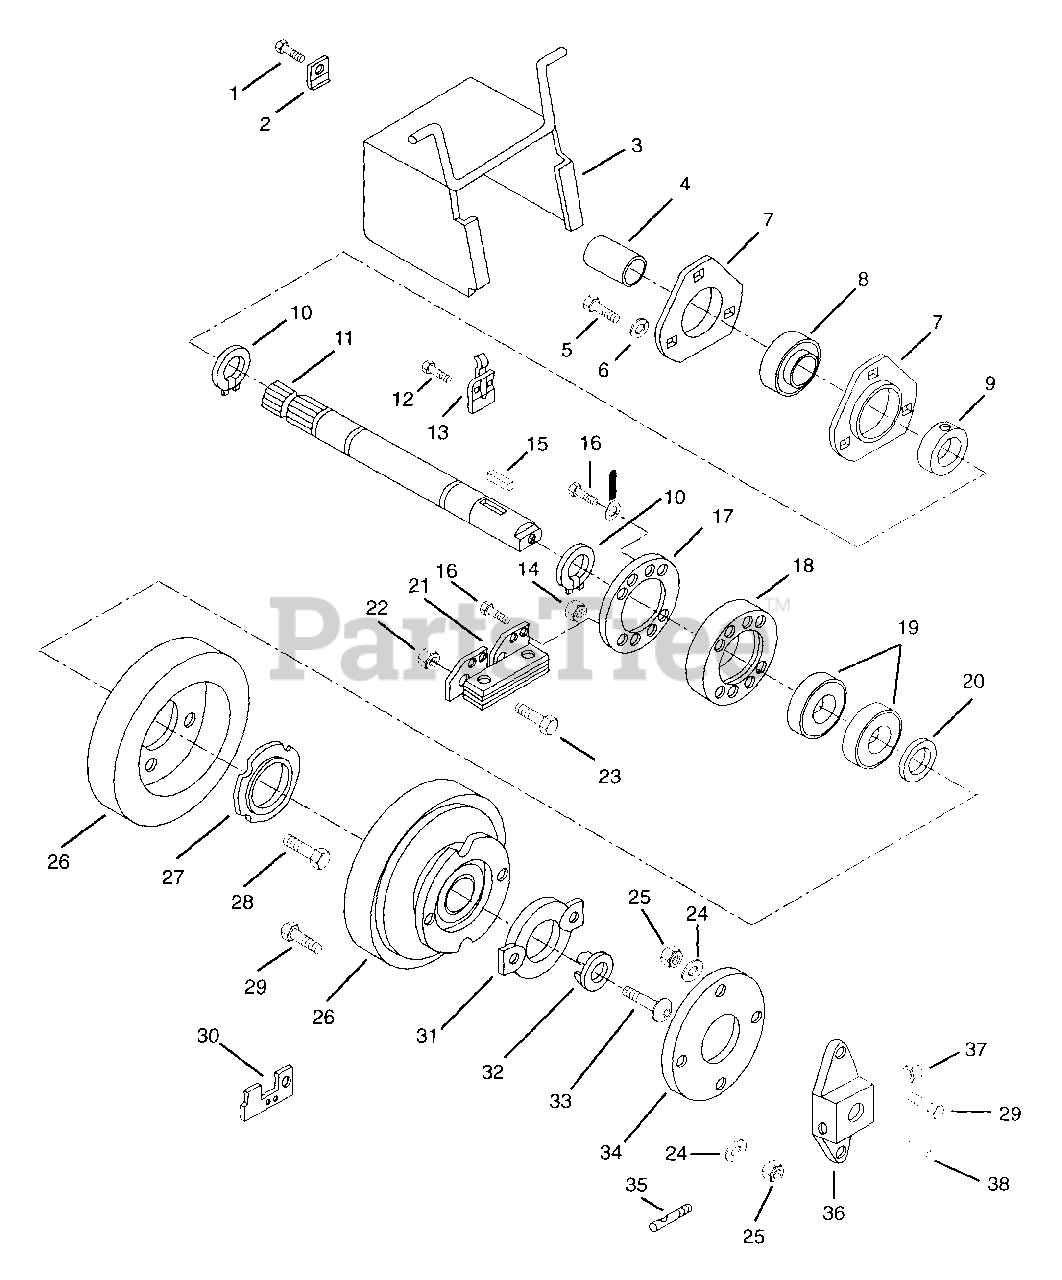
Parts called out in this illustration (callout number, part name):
1	SCR-TAP .250-20X.50 HXSLHDPL
3	PTO SHIELD
4	SHAFT COVER
5	BLT-HEX .31-18X.75 PL GR2
6	WSHR-LK .312X.097 PL HVY
7	BEARING FLANGE
8	BRG/W COLLAR 1.0 X 2.047 X.844
9	BEARING COLLAR
10	RG-RTNG-EXT 1.00X.078
12	SCR-TAP 10-24X.375 HWH PL TR
13	SNAP FASTENER
14	NUT-LK TOP 10-24 PL
15	KEY-SQ .25X1.0X.25 SAE 8630
16	SCR-TAP 10-24X.75 HWH PL TR
18	BEARING MOUNT
19	BRG-BALL 1.0X2.0X.56 (1641)
20	WSHR-FL-STL 1.031X1.375X.055
21	TORQUE BRACKET ASSEMBLY
22	NUT-LK-CTR .312-24 PL
23	BLT-HEX .31-18X1.50 PL GR5
24	WSHR-FL-STL.344X.688X.065PL
25	NUT-LK .312-18 GR A PL
26	ELECTRIC CLUTCH
27	BEARING FLANGE
28	SCR-MCH 10-24X1.25 SLPAN PL
29	BLT-HEX .31-18X.88 PL GR2
30	CONNECTOR MOUNTING CLIP
31	PILOT PLATE
32	RETAINER
33	BLT-BTHD .38-16X1.25 GR5
34	SPACER COUPLING
35	LOCK STUD
36	COUPLING
37	NUT-LK TOP .375-16 GR C YWZC
38	KEY-WDRF .188X.75X.313 SAE 9
